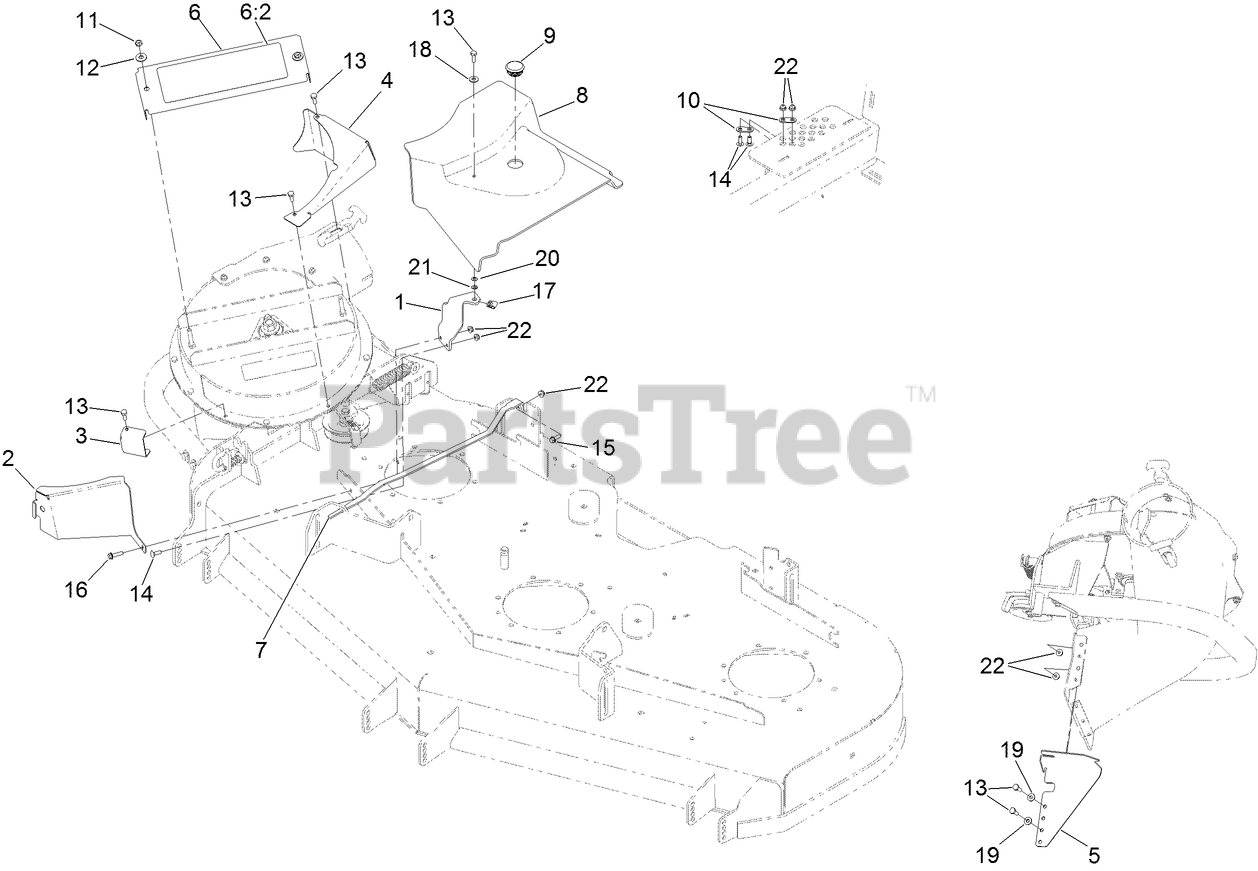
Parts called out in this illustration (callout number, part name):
1	BRACKET-COVER, BELT
2	GUARD-BAGGER [BLACK]
3	GUARD-FRONT, LEFT
4	GUARD-TOP
5	GUARD-BAGGER
6	COVER-BEARING
6:2	DECAL-DANGER
7	BRACKET-SKIRT, LOWER
8	COVER-BELT
9	PLUG-PLASTIC
10	PLATE-COVER, HOC [BLACK]
11	NUT-LOCK, NI
12	WASHER-FLAT
13	SCREW-HH
14	BOLT-CARR
15	SCREW-HHF
16	SCREW-HHF
17	NUT-SPEED
18	WASHER-FLAT
19	WASHER-FLAT
20	WASHER-FLAT
21	PUSHNUT-RETAINER, BOLT
22	NUT-HF
